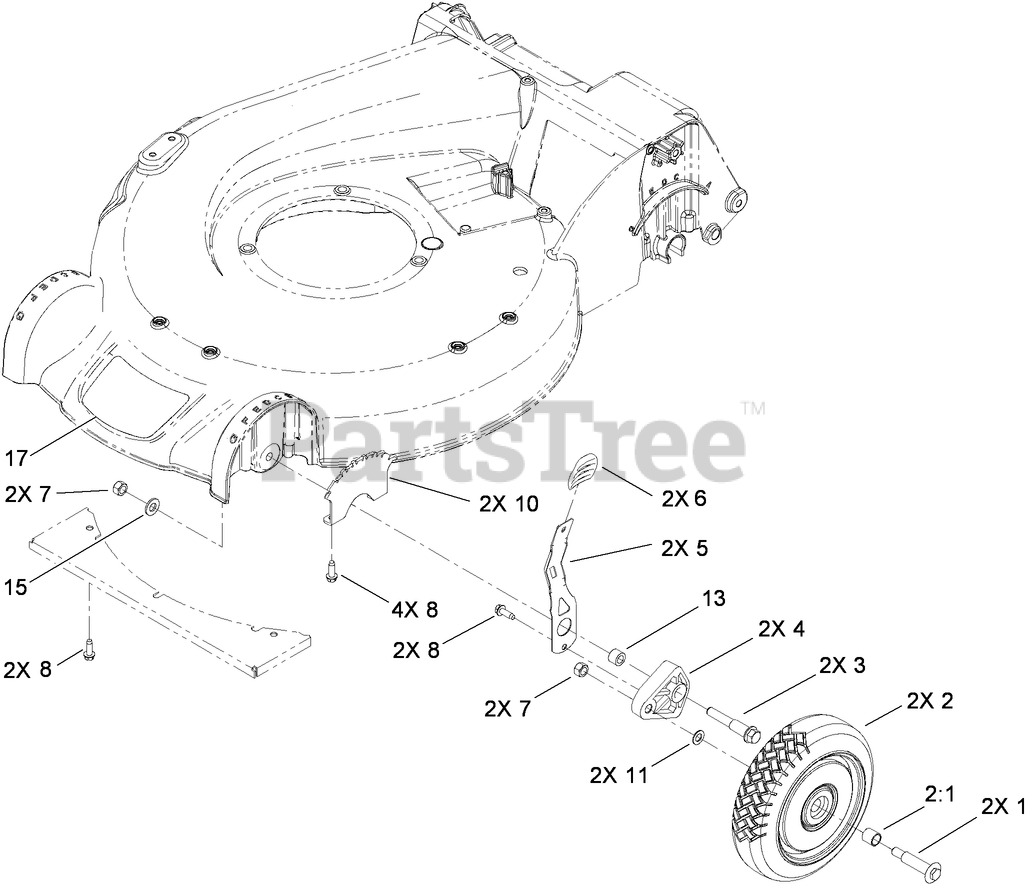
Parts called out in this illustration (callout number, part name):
1	BOLT-SHOULDER
2	WHEEL AND TIRE ASM
2:1	BUSHING
3	SCREW-SHOULDER
4	ARM-PIVOT
5	ARM-SPRING
6	KNOB-LEVER, HOC
7	LOCKNUT
8	SCREW-HWHTF
10	PLATE-HOC
11	WASHER
13	SPACER-WHEEL
15	WASHER-FLAT
17	DECAL-HOUSING
